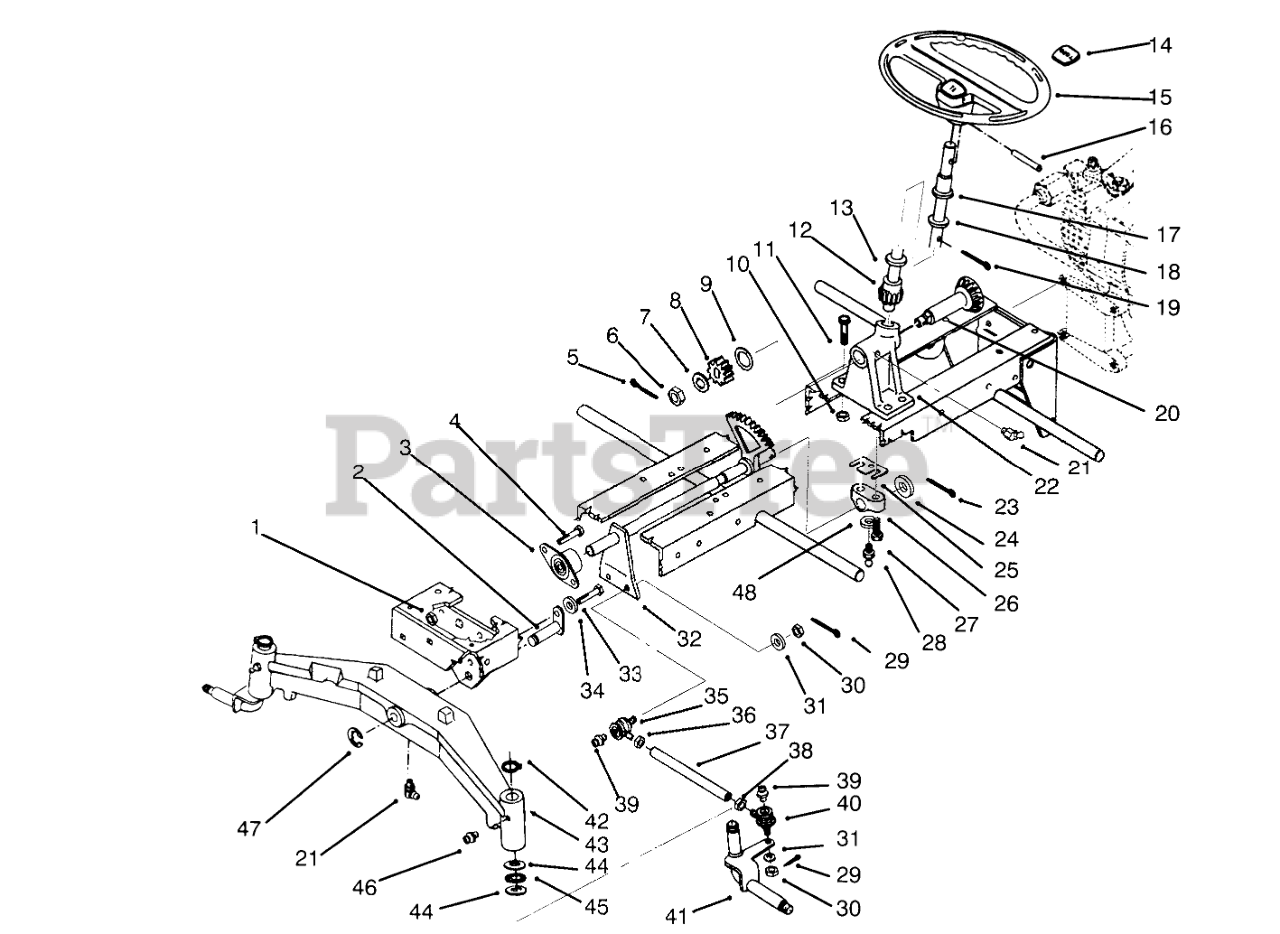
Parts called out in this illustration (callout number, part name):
1	NUT-LOCK, NI
2	PIN AND PLATE ASM
3	BEARING-FLANGED
4	SCREW-HH
5	PIN-COTTER
6	Nut
7	WASHER-FLAT
8	PINION-SPUR
9	WASHER
10	NUT-LOCK, NI
11	SCREW-HH
12	WLDMT-STRG SHAFT
13	O-RING
14	STRG-WHL INSERT TORO
15	Steering Wheel (Incl. Ref. #14)
16	PIN-ROLL
17	BEARING-FLANGED
18	WASHER-SHIM
19	PIN-COTTER
20	WLDMT-C SHAFT
21	FITTING-GREASE
22	Steering Support
23	PIN-COTTER
24	WSHR-.765X1.125X.060
25	SHIM-.010
26	BLOCK-BEARING
27	Bolt
28	ZERK FITTING
29	PIN-COTTER
31	WASHER
32	Shaft
33	SCREW-HH
34	WASHER-LOCK
35	Tie Rod End-Thread RH (Incl. Ref. #30)
36	NUT-JAM
37	Tube
38	NUT-HEX JAM 9/16-18
39	FITTING-GREASE
40	Tie Rod End-Thread LH (Incl. Ref. #30)
41	Spindle
42	RING-RETAINING
43	Axle-Front
44	WASHER-THRUST
45	BEARING-THRUST
46	FITTING-GREASE
47	E-RING
48	WASHER-LOCK
